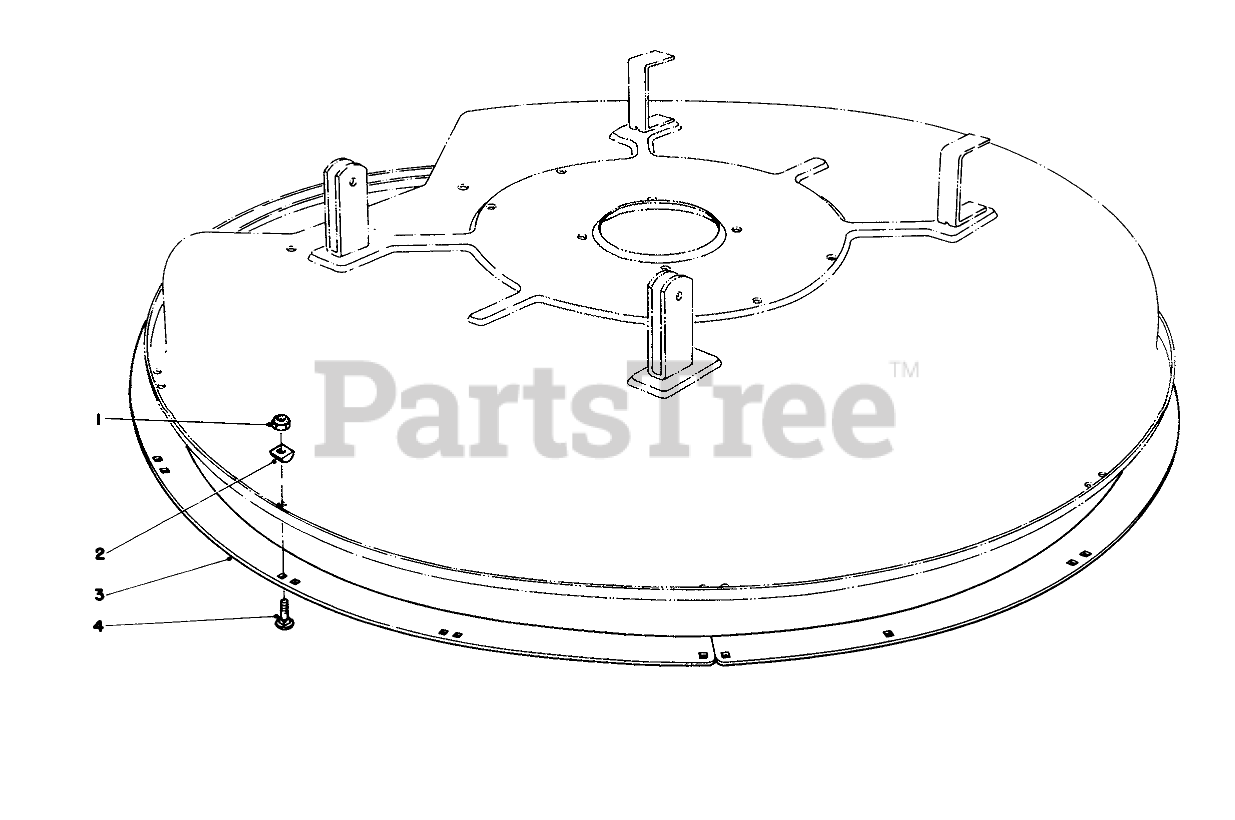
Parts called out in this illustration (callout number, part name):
1	NUT-LOCK, NI
2	DECK RING SPACER
3	DECK RING B
4	BOLT-CARR
